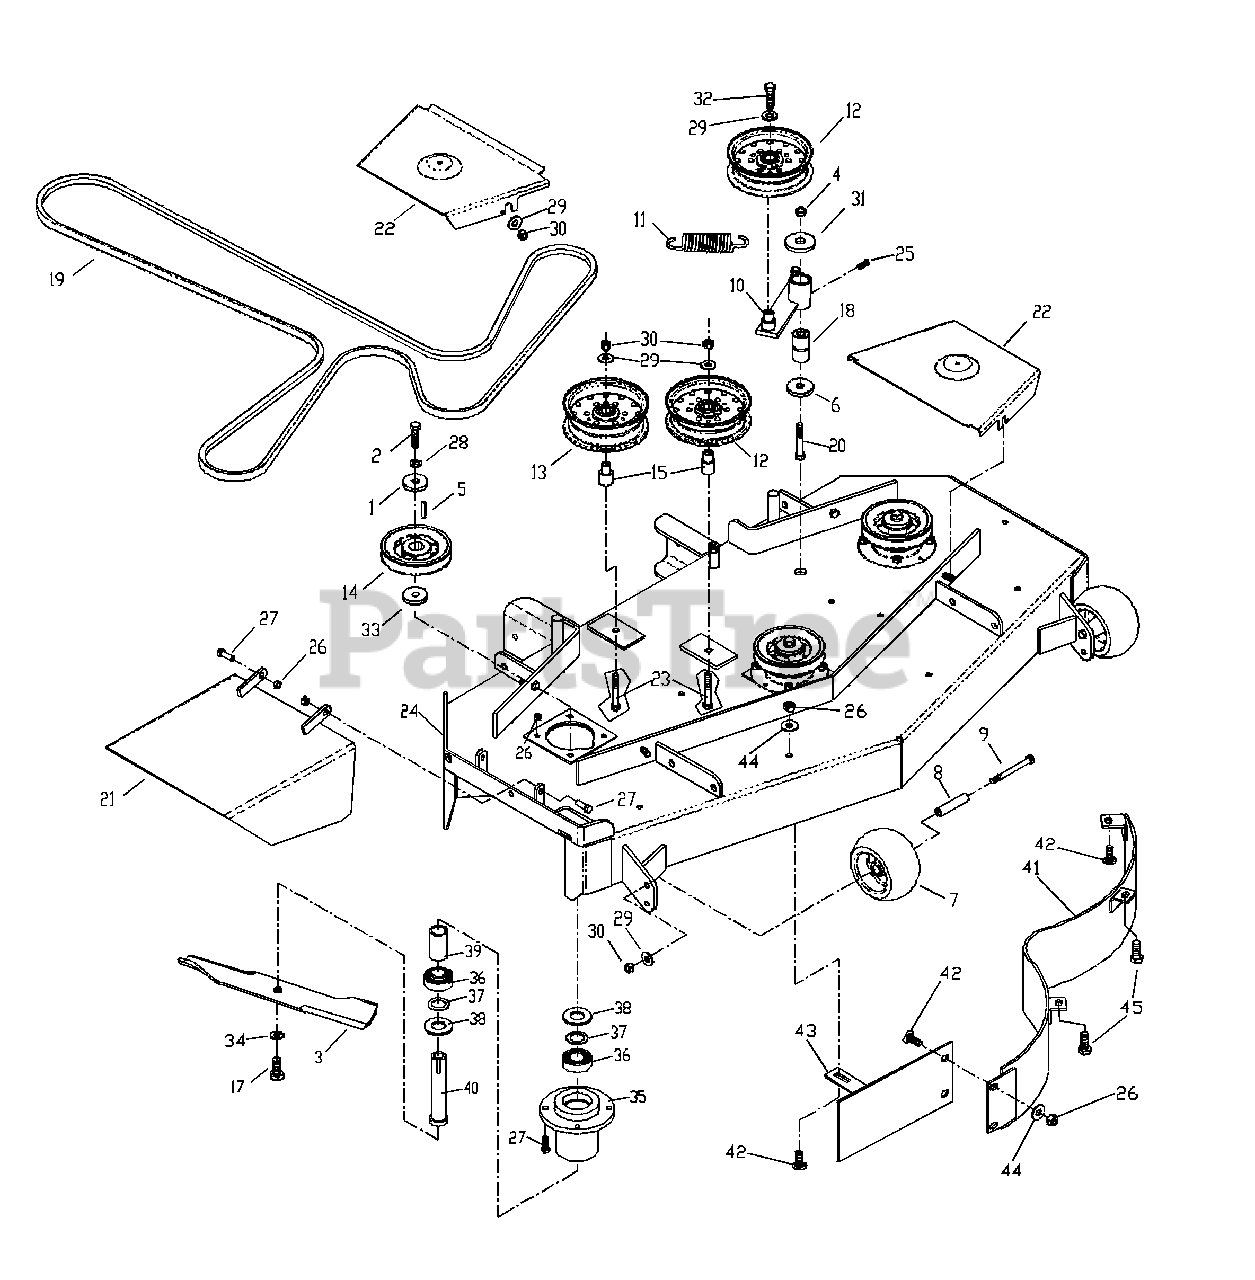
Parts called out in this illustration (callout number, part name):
1	HEAVY WASHER
2	HCS 7/16 X 1.500
3	BLADE 16.250
4	NUT 1/2 NYLOC
5	KEY 1/4 X 1.125
6	SUPPORT WASHER
7	ANTI-SCALP ROLLER
9	HCS 3/8 X 3.500
12	IDLER PULLEY
13	IDLER PULLEY
15	IDLER BUSHING
16	COMPLETE HOUSING
17	HCS 5/16 X 1.250
18	PIVOT BUSHING
19	BELT
20	HCS 1/2 X 3.250
21	DEFLECTOR CHUTE
22	BELT SHIELD
23	HCS 3/8 X 2.500
24	DECK W/DECALS
25	ZERK
26	NUT 5/16 CTR. LOCK
27	HCS 5/16 X 1.000
28	WASHER 7/16 LOCK
29	WASHER 3/8 FLAT
30	NUT 3/8 CTR. LOCK
31	WASHER 1/2 FLAT
32	HCS 3/8 X 1.00 SERR. HD.
33	MACH. BUSHING
34	WASHER 5/8 LOCK
36	BEARING
37	MACH. BUSHING
38	MACH. BUSHING
41	MAIN BAFFLE
42	RHSNB 5/16 X .625
43	CENTER BAFFLE
44	WASHER 5/16 FLAT
45	HCS 5/16 X .750
